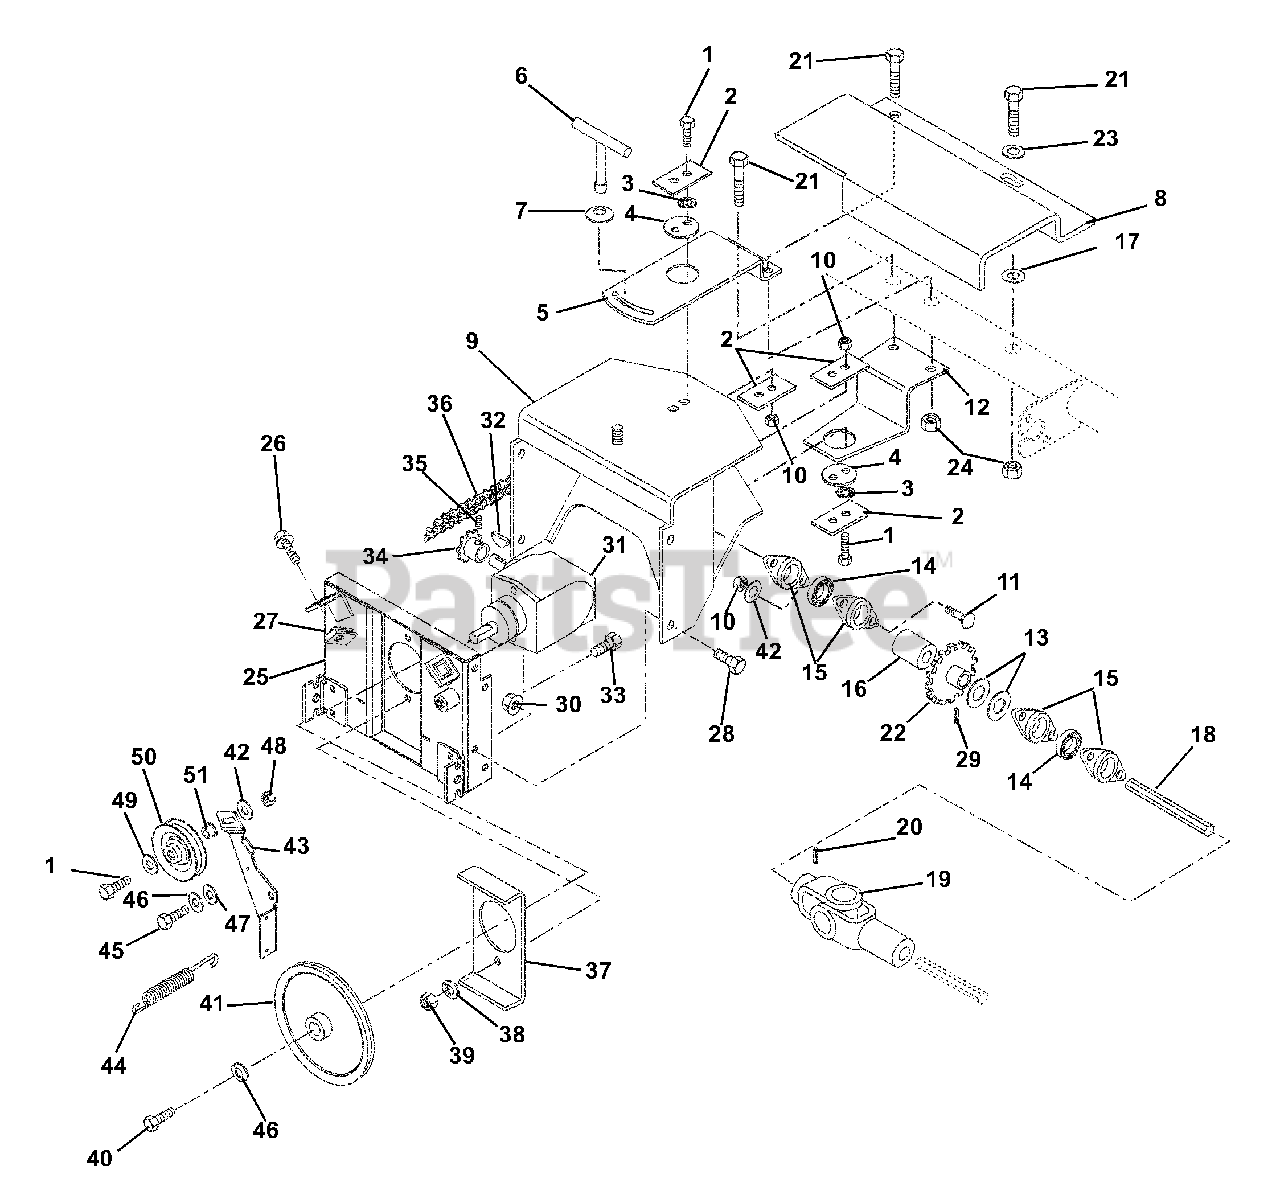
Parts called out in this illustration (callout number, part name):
1	@BLT-HEX .31-18X1.25 GR5 YWZC
2	RETAINER
3	@WSHR-LK-EXT.326X.599X.031YWZC
4	PIVOT CENTER
5	PLATE, TOP MOUNT
6	T-LOCK HANDLE
7	WASHER, CUPPED SERRATED, .375
8	GUARD, SHAFT
9	FRAME, ADAPTOR
10	@NUT-LK-CTR .31-18 YWZC
11	@BLT-RDHDSQNK .31-18X.75 G5YZ
12	PLATE, BOTTOM MOUNT
13	WSHR-FL-STL 1.015X1.500X.125
14	BRG-BALL .884HEXX52MMX1.07
15	BEARING FLANGE
16	SPACER 1.006X1.307X.500
17	WSHR-FL-STL .390X.88X.18 YWZC
19	JOINT, UNIVERSAL
20	PIN-ROLL .188X1.50
21	@BLT-HEX .38-16X3.25 GR5 YWZC
22	SPROCKET
23	@WSHR-FL-STL.406X.812X.065 YWZ
24	@NUT-LK-CTR .38-16 YWZC
25	PLATE, MOUNTING-BROOM
26	BLT-SERHFWH .38-16X.75 YWZC
27	NUT-RETNR .38-16 TINRMAN
28	@BLT-HEX .38-16X.75 GR5 YWZC
29	PIN-ROLL .188X1.75
30	@NUT-LK-CTR .38-16 YWZC
31	GEAR BOX ASSEMBLY
32	KEY-WDRF .188X.75X.313 SAE 9
33	@BLT-HEX .38-16X1.25 GR5 YWZC
34	SPROCKET
35	SCR-SET .25-20X.38 SKHCUPNL OH
36	ROLLER CHAIN #41 - 34 PITCHES
37	PLATE, STIFFENER
38	@WSHR-LK .38X.094 REG YWZC
39	@NUT-HEX .38-16 YWZC
40	BLT-HEX .31-24X.75 YWZC GR5
41	PULLEY, 4L W/HUB, .87 X 8.5
42	@WSHR-FL-STL.38X.875X.083 YWZC
43	ARM, AUGER/BRAKE-HIGH W/LINING
44	SG-TENS .06X.492X5.25 WLD 11
45	@BLT-HEX .31-18X.75 GR5 YWZC
46	WSHR-LK .312X.097 HVY YWZC
47	WSHR-FL-STL .328X1.0X.094 YWZC
48	@NUT-LK-TOP-FLG .31-18 YWZC
49	@WSHR-FL-STL.344X.688X.065YWZC
50	IDLER
51	SPCR, BRG .315X.50X.688X.281
52	@BLT-HEX .31-18X1.25 GR5 YWZC
